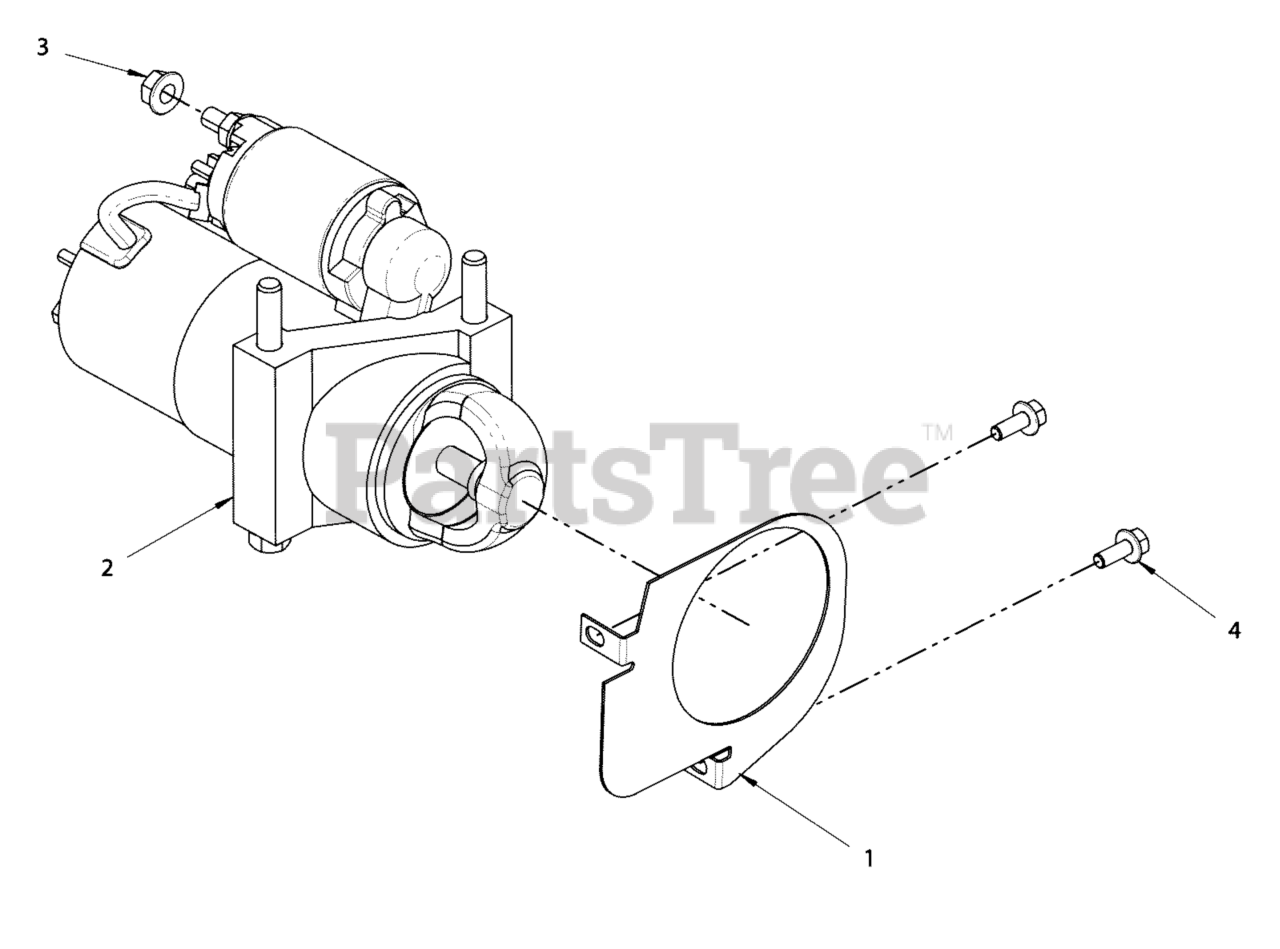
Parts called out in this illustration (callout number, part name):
1	*COVER, STARTER MOUNT
3	*NUT
4	*BOLT
